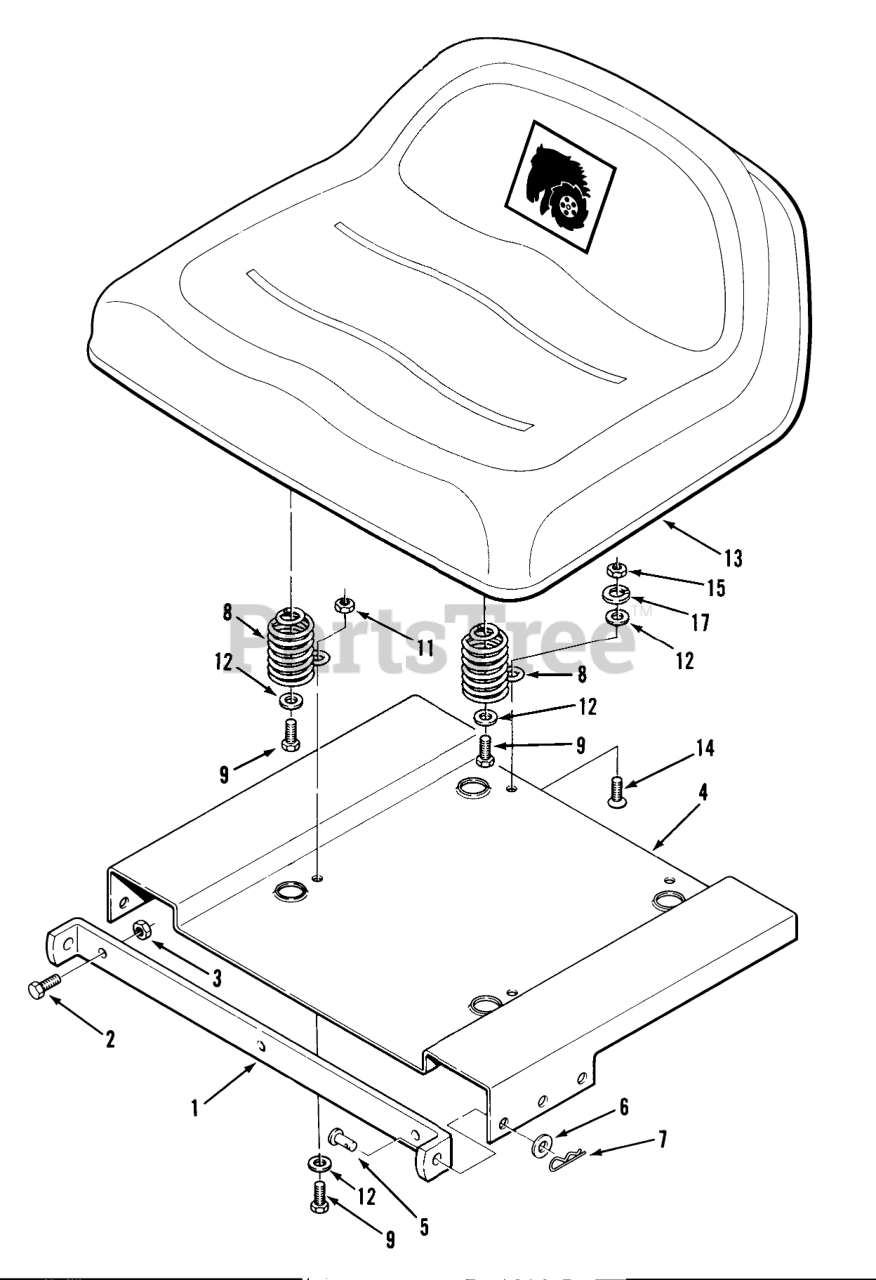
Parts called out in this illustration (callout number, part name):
1	BRACKET-SEAT MOUN R
2	Bolt
3	Nut
4	Seat Pivot Plate
6	WASHER-SPRING
7	Hairpin
8	SPRING SEAT
9	Bolt
11	Nut
12	WASHER 5/16 SAE
13	Seat
14	Screw 5/16-18 X 3/4
15	Nut
17	Lockwasher
